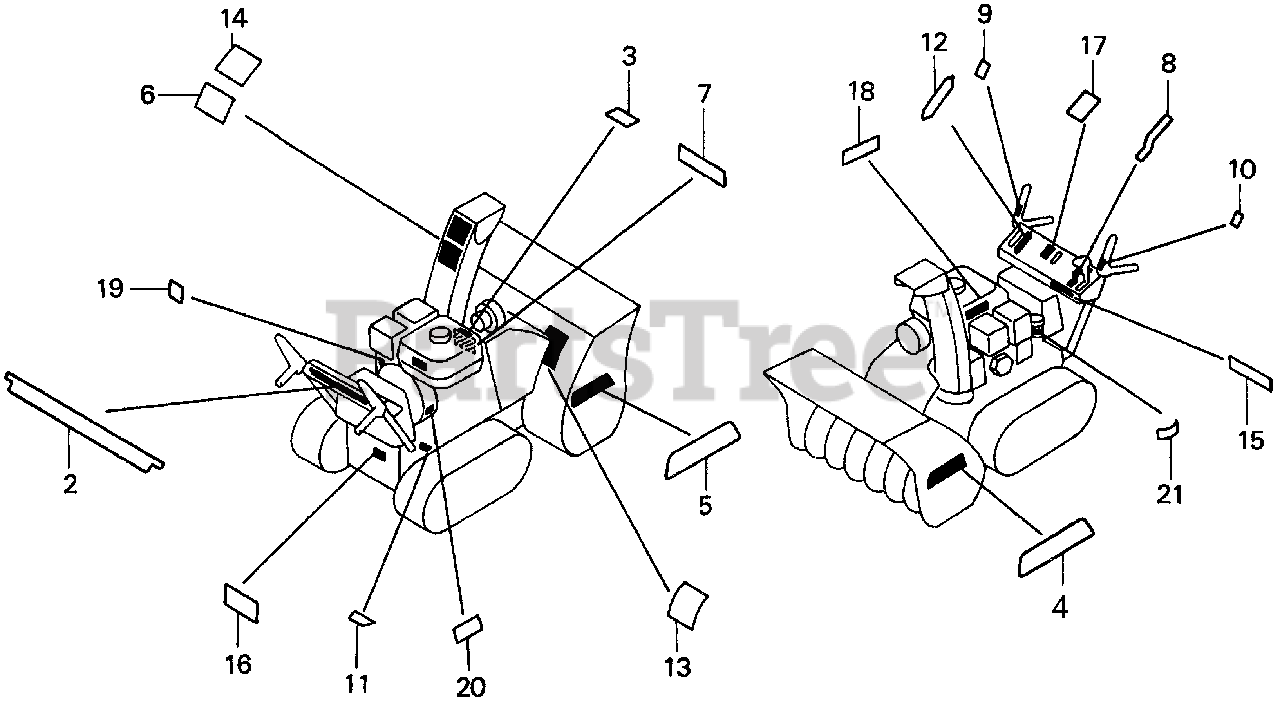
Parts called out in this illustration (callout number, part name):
2	LABEL, OPERATION (ENGLISH)
3	MARK, HONDA EMBLEM
4	MARK, L. STRIPE
5	MARK, R. STRIPE
6	LABEL, WARNING (ENGLISH)
7	LABEL, WARNING FUEL (ENGLISH)
8	MARK, CHANGE INDICATION
9	MARK, AUGER CLUTCH (ENGLISH)
10	MARK, CLUTCH (ENGLISH)
11	MARK, HEIGHT ADJUSTING
12	MARK, CHUTE CONTROL OPERATION (ENGLISH)
13	MARK, HOUSING DANGER (ENGLISH)
14	MARK, DISCHARGE DANGER (ENGLISH)
15	MARK (H.S.T.)
16	MARK, INDICATION (H.S.T.)(ENGLISH)
17	MARK, THROTTLE (ENGLISH)
18	MARK, EX. CAUTION (ENGLISH)
19	MARK, FUEL INDICATION (ENGLISH)
20	MARK, OIL CAUTION (ENGLISH)
21	LABEL, OIL RECOMMENDATION (ENGLISH)
